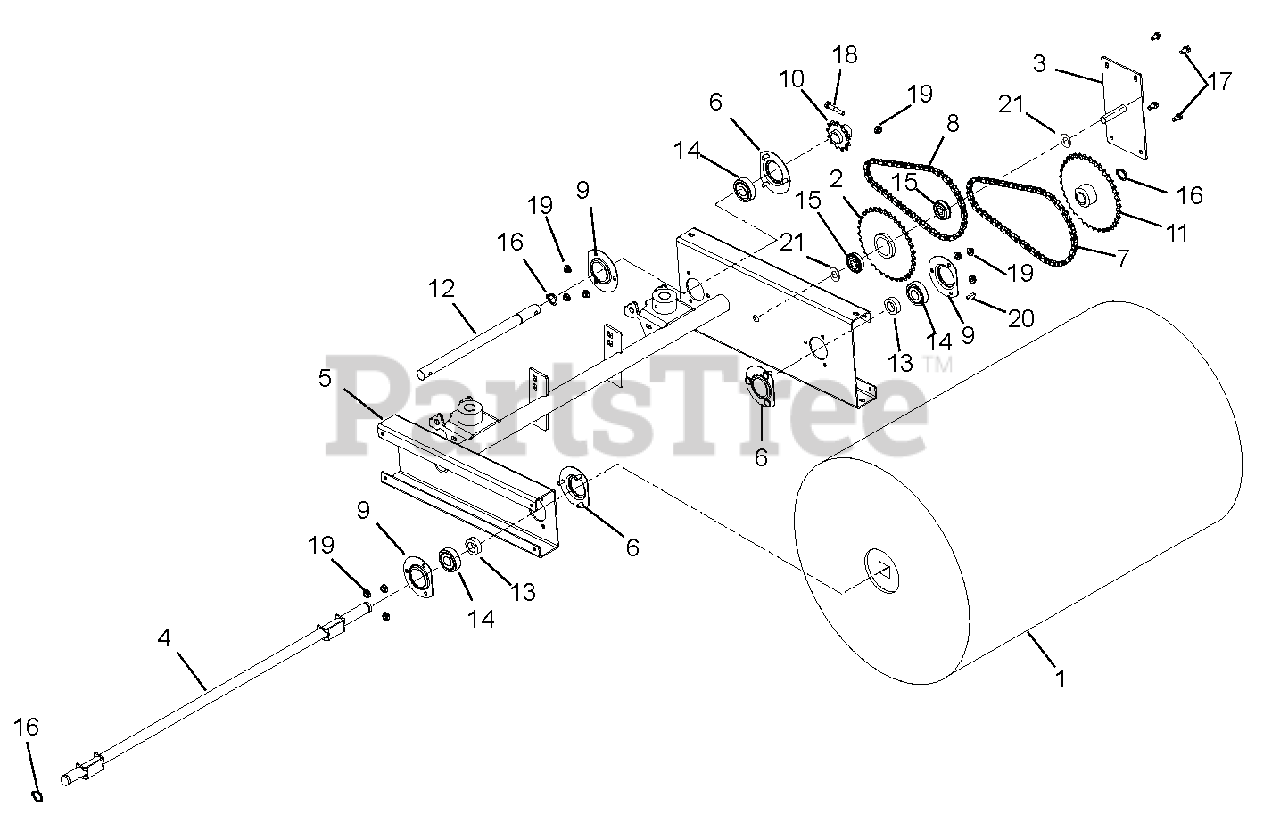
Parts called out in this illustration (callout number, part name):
1	BRUSH, 18"DIA X 28"WIDE
2	SPROCKET, REDUCTION IDLER
3	PLATE, IDLER REDUCTION MOUNT
4	SHAFT, 28" BRUSH
5	FRAME, POWER BROOM
6	BEARING FLANGE
7	CHAIN, #40-54 LINKS
8	CHAIN, #41-50 LINKS
9	BEARING FLANGE
10	SPROCKET, DRIVE
11	SPROCKET, DRIVEN
12	SHAFT, TRANSMISSION
13	SPACER .755X1.250X.370
14	BRG-BALL .750X1.750X.50
15	BRG-BALL .50X1.38X.438 SEALED
16	RG-RTNG-EXT .689X.078
17	SCR-TAP .25-20X.50 HWH TR YWZ
18	@BLT-HEX .25-20X1.75 GR5 YWZC
19	@NUT-LK-TOP-FLG .25-20 YWZC
20	KEY-WDRF .188X.75X.313 SAE 9
21	@WSHR-FL-STL.563X1.38X.109YWZC
